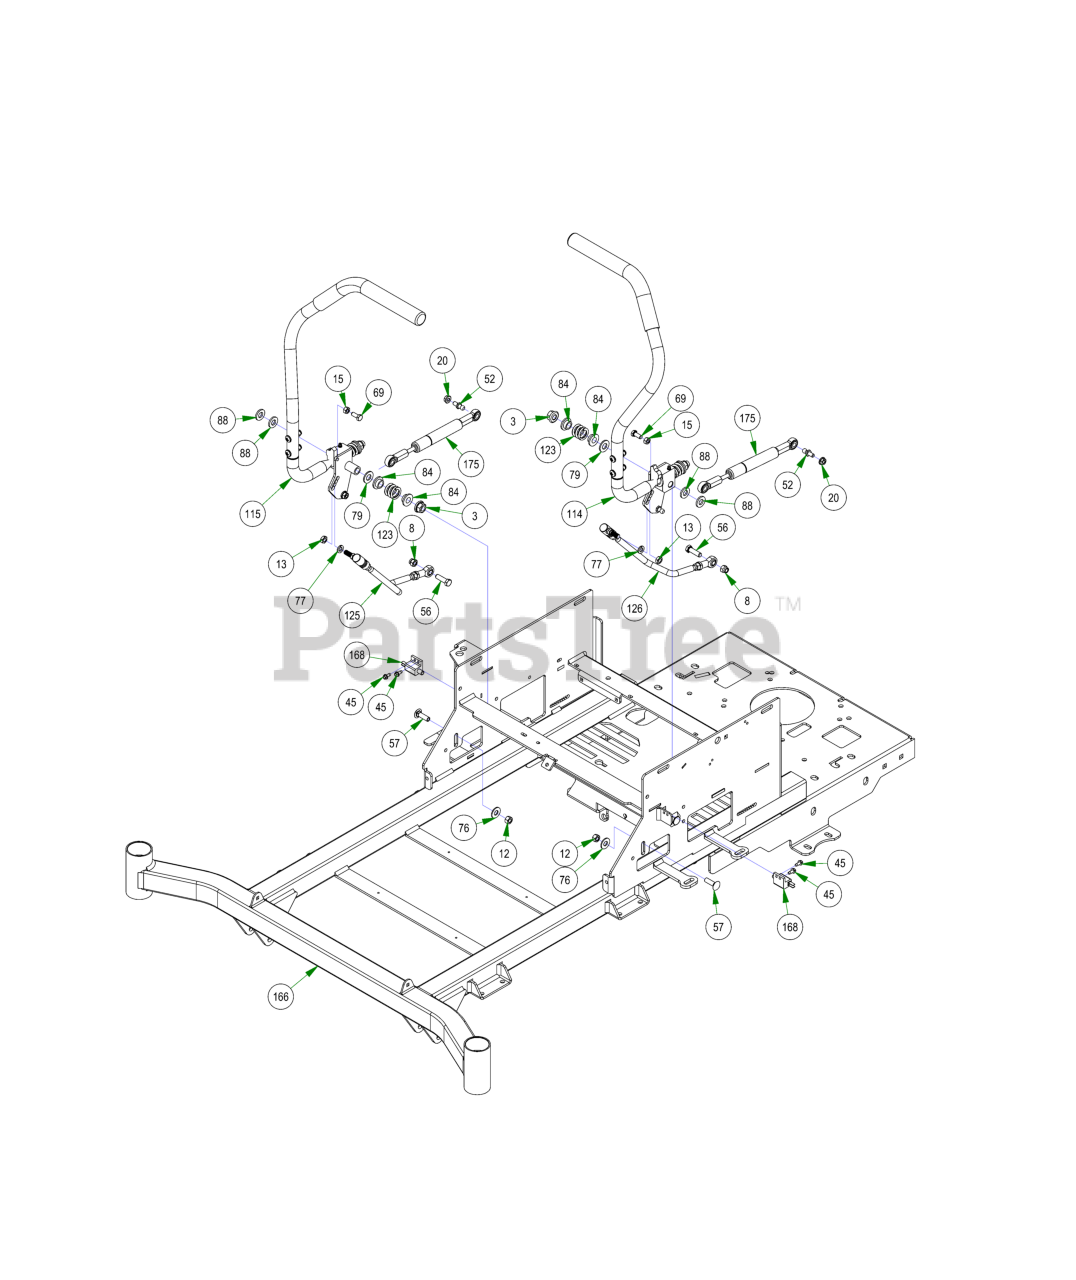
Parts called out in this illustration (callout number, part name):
3	1/2-13 HEX FLANGE AUTO OVAL LOCKNUT (GR.F) ZINC/WAX
8	3/8-16 NYLON INSERT LOCKNUT ZINC
12	3/8-16 HEX NUT ZINC
13	3/8-24 HEX NUT ZINC YELLOW
15	5/16-18 HEX NUT ZINC
20	5/16-18 HEX SERRATED FLANGE NUT HARD/ZINC
45	12-24 X 1/2 HEX WASHER UNLSOT F TCS ZINC
52	10mm Damper Ball Stud-Steering
56	3/8-16 X 1-1/4 HEX CAP SCREW (GR.5) ZINC
57	3/8-16 X 1-1/4 CARRIAGE BOLT ZINC
69	5/16-18 X 3/4 HEX CAP SCREW (GR.5) ZINC
76	3/8 FLAT WASHER USS (1" OD) ZINC
77	3/8 SPLIT LOCKWASHER ZINC
79	1/2 SAE FLAT WASHER (1-1/16" OD) GR.8 ZINC YELLOW
84	.525 ID SHOULDER WASHER NYLON
88	.505 ID X 1.000 OD X .125 THICK FLAT WASHER NYLON
114	ZT Steering Arm Assembly, Left Hand
115	ZT Steering Arm Assembly-Right Hand
123	Drive Lever Spring
125	Push Rod-Right
126	Push Rod-Left
166	2022 MZ/ZT 54"-60" Frame
168	Safety Switch
175	ZT Avenger Steering Dampener
